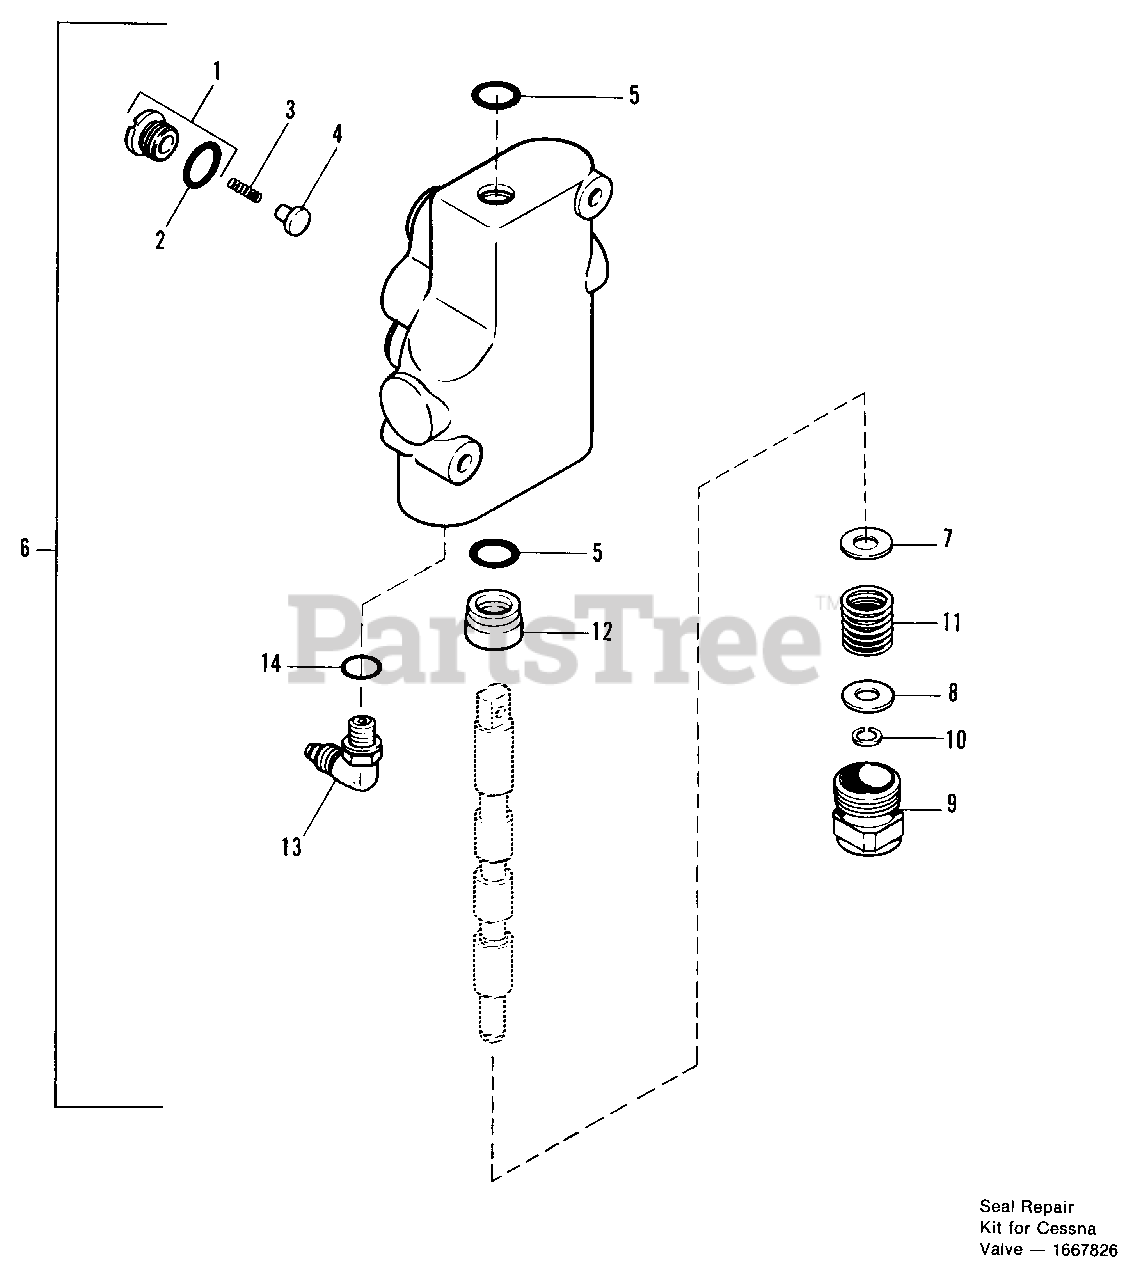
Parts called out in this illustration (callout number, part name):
2	O-RING
5	O-RING
6	VALVE ASSY.
10	RING, Retaining
14	O-RING
